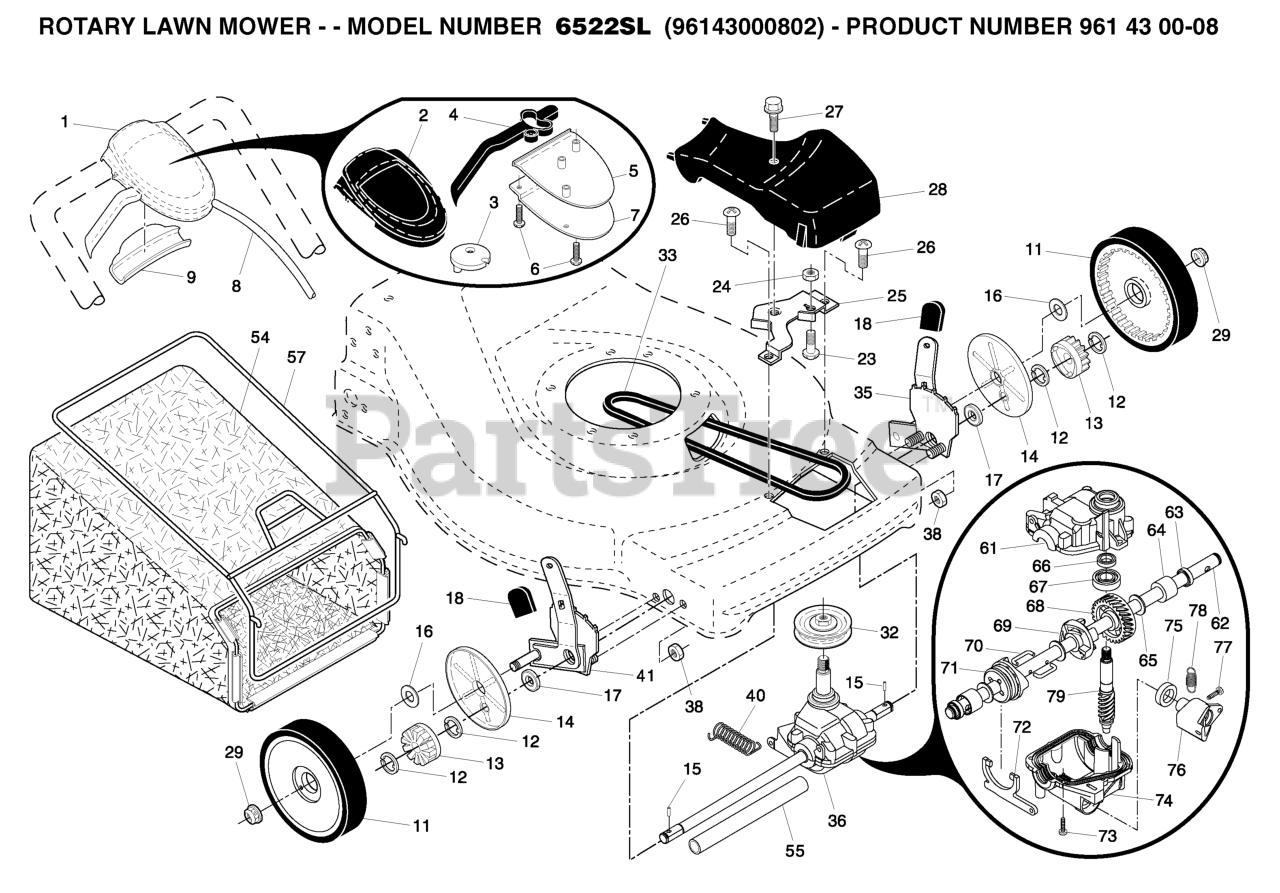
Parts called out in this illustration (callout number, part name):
1	RP CONTROL.DR.EZ
2	CASE.TOP.GRAY
3	PULLEY.CAM.DRIVE.CONTROL.HV
4	LEVER, AUTOWALK DRIVE CONTROL
5	CASE BOTTOM
6	SCREW, PHILLIPS HEAD 10 X 5/8
7	BRACKET.DRIVE.CONTROL.MOUNT.BL
9	EZ WALK SNAP COVER PLATE
11	WHEEL.8X1.75.5SPK.RAD.GREY
12	E-RING 7/16 RE
13	PINION
14	COVER.DUST.WHEEL
15	PAWL.DRIVE
16	WASHER FLUT
17	BEARING
18	KNOB.DELUXE.GRAY
23	HINGE SCREW
24	NUT.HEX.FLANGE.1/4
25	BRKT.CABLE/BELT.GUARD.
26	SCREW.HEX.WSH
27	SCREW, HEX HD TAPPING #10-24 1
29	HEX FLANGE LOCKNT
32	RP PULLEY.DRIVE.EZ
33	BELT.DRIVE.FG
35	RP KIT.ADJUSTER.ASM.EZ
36	TRANSMISSION.22.FWGD
38	LOCKNUT.NYLOC.1/4-20
40	SPRING RETURN
41	KIT.ADJUSTER.AS.EZ RT
55	DRV SHAFT TUBE PM
57	FRAME.GBAG.EZ.EMPTY
61	GEARCASE.HOUSING
62	OUTPUT.SHAFT.(12245)
63	SEAL.OUTPUT.SHAFT
66	SEAL INPUT SHAFT
68	GEAR.27.TEETH.WALK.MOWER
70	WIRE, FORMED (15966)
74	GEARCASE.HOUSING.LOWER
77	SCREW.LEVER.
79	SHAFT INPUT (13041)
